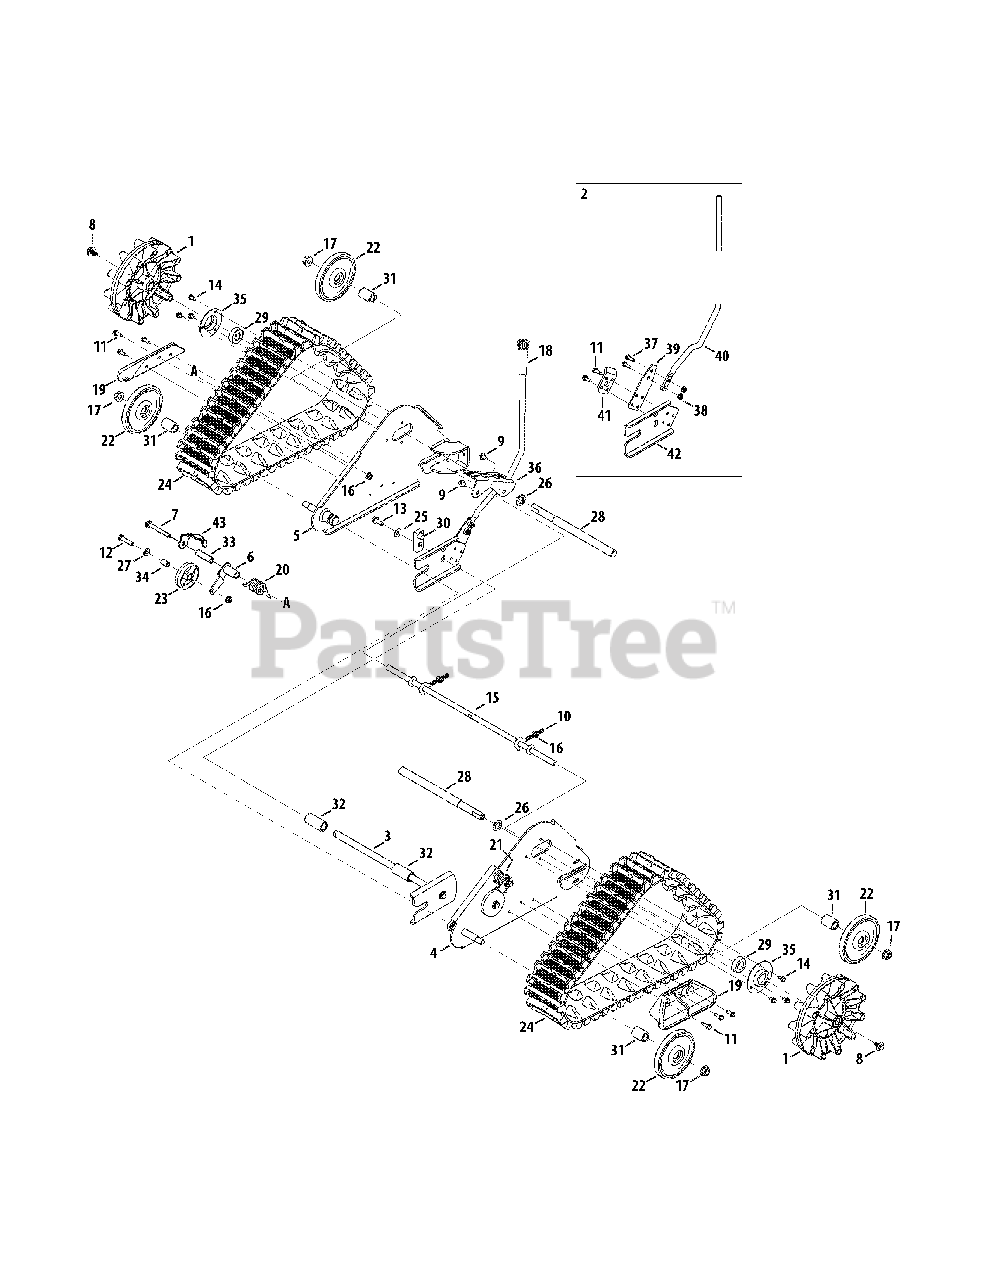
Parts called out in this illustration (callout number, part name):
1	Track Drive Wheel
2	Height Adjustment Lever Assembly
3	Pivot Bracket Assembly
4	Track Mount Plate Assembly, LH
5	Track Mount Plate Assembly, RH
6	Pivot Tension Bracket Assembly
7	Hex Screw, 5/16-18, 2.50, Gr5
8	Screw, 5/16-24 x .750
9	Hex Washer Screw, 5/16-18 x .875
10	Eye Bolt, 5/8 x 2.375, 5/16-18
11	Hex Washer Screw, 1/4-20 x .625
12	Hex Cap Screw, 5/16-18 x 1.50
13	Hex Washer Screw, 5/16-18 x .875
14	Hex Washer Screw, 1/4-20 x .625
15	Rear Wheel Axle
16	Nut, Flange lock, 5/16-18
17	Flange Lock Nut, 1/2-13
18	Grip, .5 ID x 3.45
19	Track Skid
20	Torsion Spring
21	Torsion Spring
22	Wheel, 5.00 OD
23	Track Tension Wheel
24	Track, 61mm x 22 Pitches
25	Washer, Bell, .340 x .872
26	Flat Washer, .672 x 1.125 x .125
27	Flat Washer, .344 x .750 x .120
28	Axle, .75 OD x 11.06 LG
29	Ball Bearing, 17 x 40 x 12
30	Height Adjustment Adapter
31	Spacer, .63 x 1.00 x 1.42
32	Spacer, .632 x 1.00 x 1.42
33	Sleeve, .33 x .50 x 1.73
34	Sleeve, .33 x .50 x .75
35	Cup Bearing
36	Height Adjustment Index Bracket
37	Hex Cap Screw, 1/4-20 x .75
38	Nut, Flangelock, 1/4-20
39	Lever Mounting Bracket
40	Height Adjustment Lever
41	Lever Pivot Bracket
42	Height Adjustment Pivot Bracket
